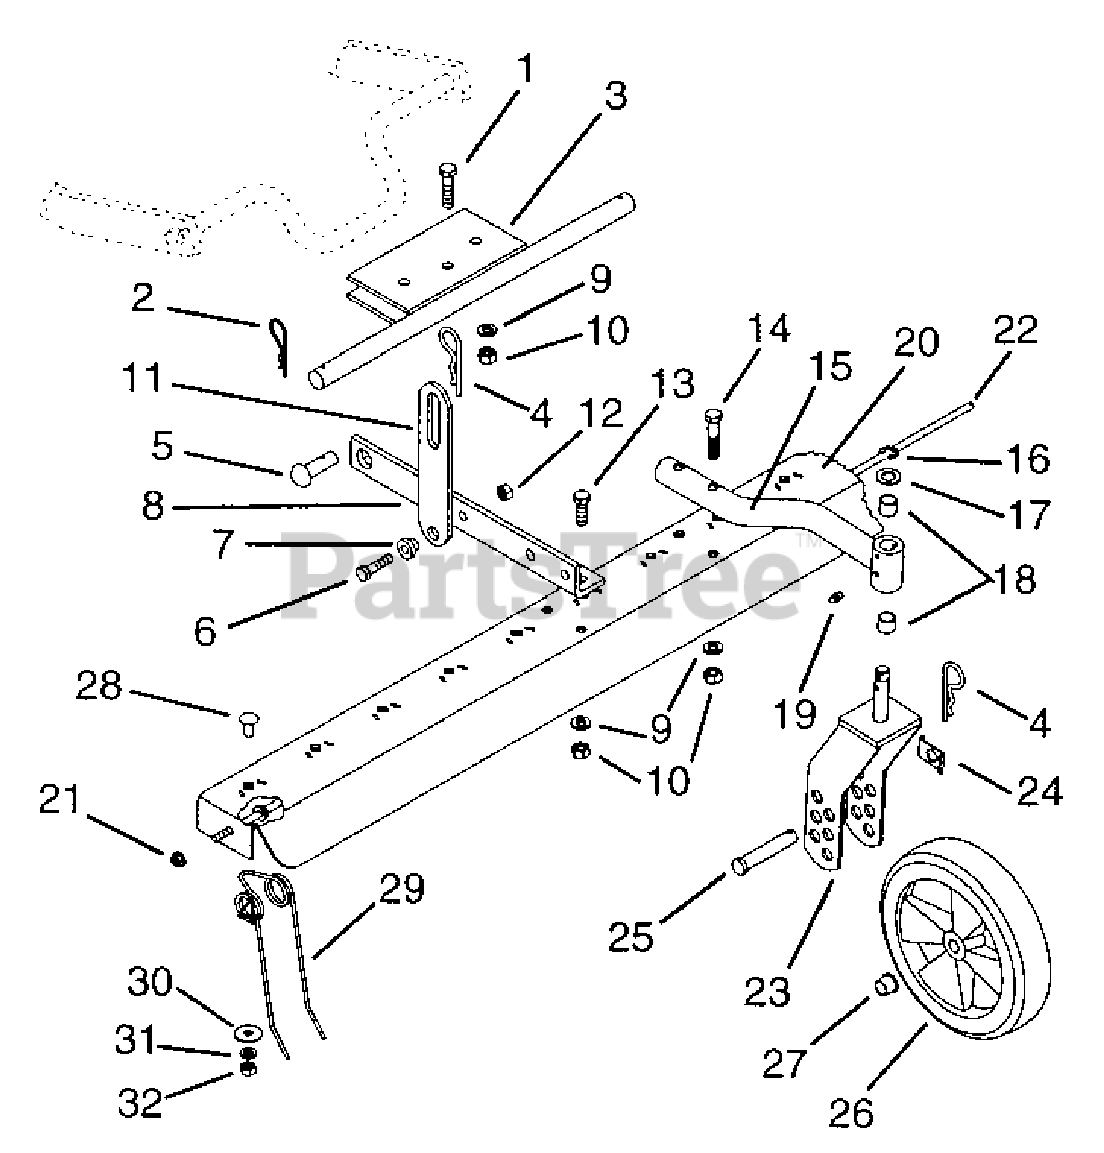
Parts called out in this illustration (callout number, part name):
1	Bolt-Hex .38-16 x 1.50
2	Pin-Hair Internal .09 x .188
3	Bracket-Weldment
4	Pin-Hair-Internal .15 x 2.937
5	Clevis Pin .50 x 1.25
6	Bolt-Hex .31-18 x 1.25
7	Bushing-Flange .344 x .468 x .485 x .750
8	Angle Bracket
9	Washer-Lock .38-16
10	Nut-Hex .375-16
11	Limiting Arm
12	Nut-Hex .31-18
13	Bolt-Hex .38-16 x 1.00
14	Bolt-Hex .38-16 x 1.75
15	Wheel Bracket Weldment
16	Ring-Retaining-External .438 x .035
17	Washer-Flat-Steel .505 x .880 x .072
18	Bushing-Sleeve .500 x .625 x .500
19	Fitting-Lube .25-28 x .256
21	Nut-Locking-Ctr .25-20
23	Wheel Yoke Weldment
24	Axle-Tab
25	Clevis-Pin
26	Wheel .5 Bore-1.5 Hub
27	Bushing-Flange .500 x .625 x .500 x .750
28	Bolt-Round Head Square Neck .31-18 x .75
29	Tine Staring
30	Washer-Flat-Steel .328 x 1.0 x .094
31	Washer-Lock .312 x .097
32	Nut-Hex .31-18
